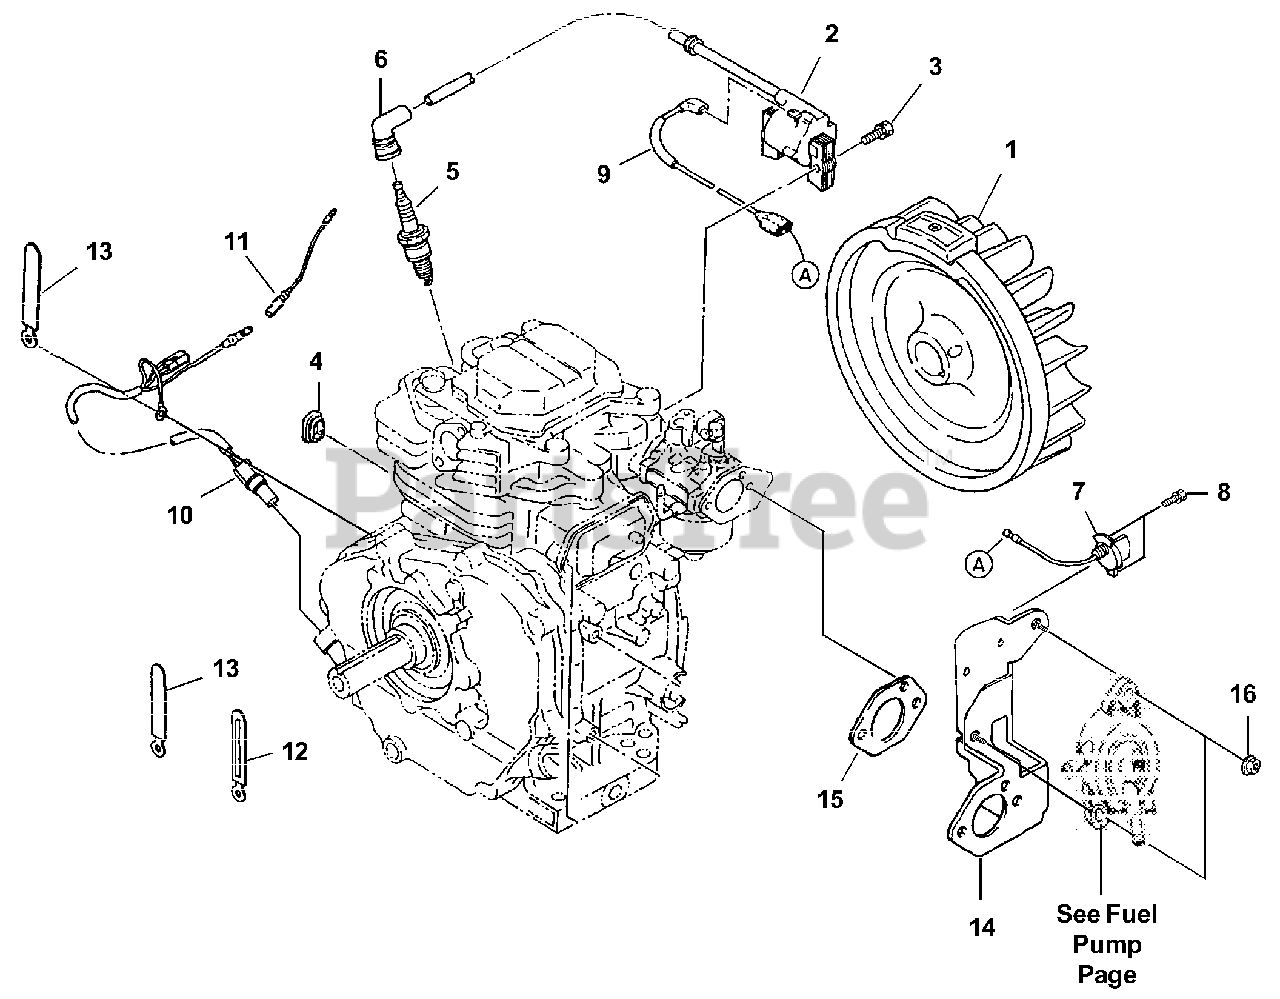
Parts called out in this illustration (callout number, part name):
1	Flywheel
2	Ignition coil cp
3	Bolt and washer Ay
4	Grommet
5	Spark plug
6	Spark plug cap
7	Switch AY
8	Tapping screw
9	Wire 3 cp
10	Oil Sensor cp
11	Wire 18 cp
12	Clamp cp
13	Clamp
14	Bracket, Fuel Pump
15	Gasket, Air Cleaner
16	Nut
